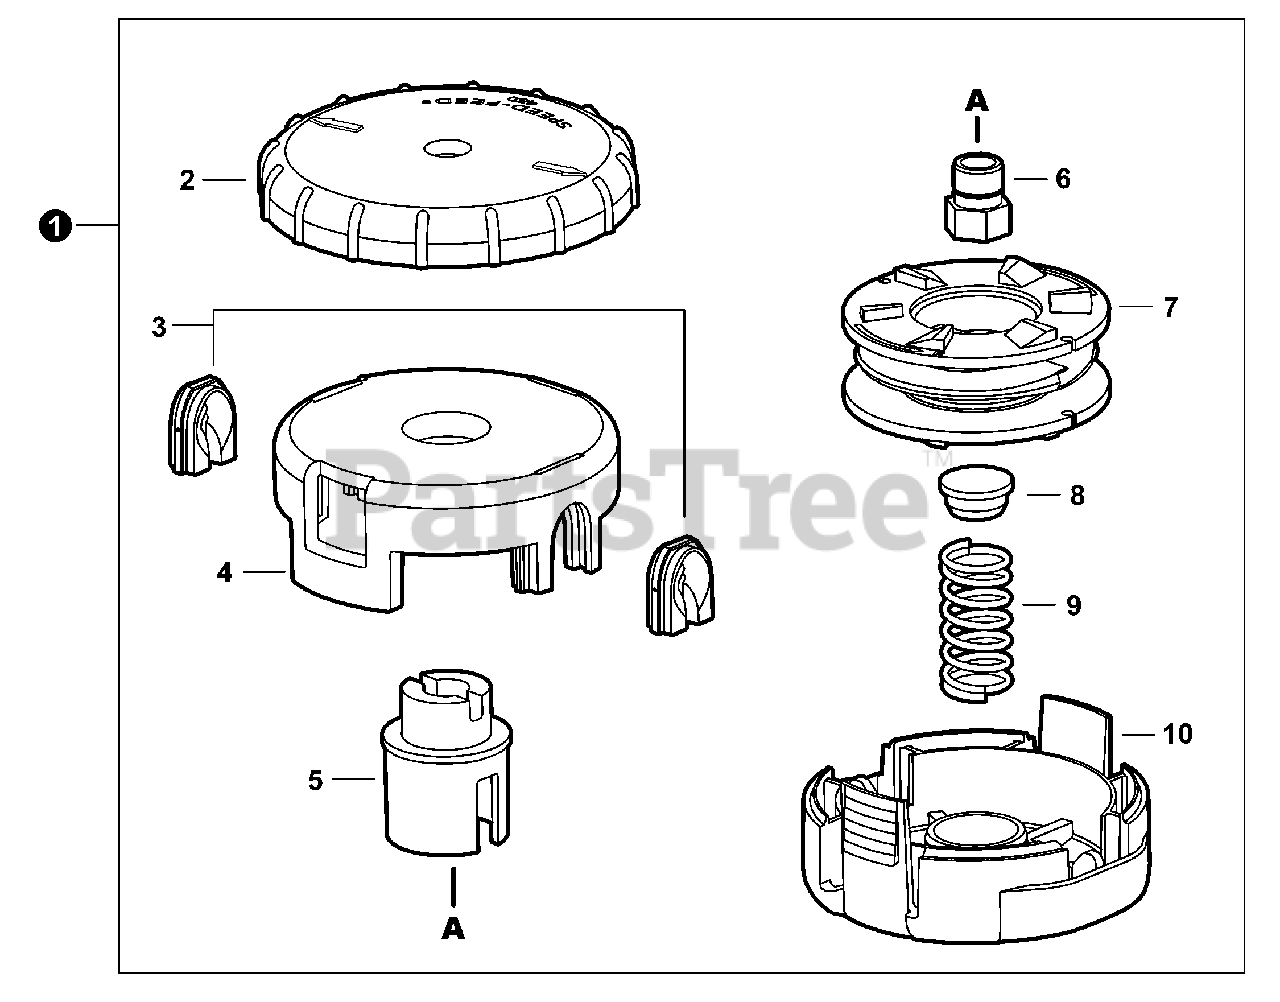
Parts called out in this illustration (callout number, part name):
1	TRIMMER HEAD, SPEED-FEED® 450
4	HOUSING, SPOOL
5	HUB, SPOOL
6	BUSHING LH M10×1.25 FEMALE
7	SPOOL LH
8	CAP, SPRING
9	SPRING, COMPRESSION
10	COVER, SPOOL
